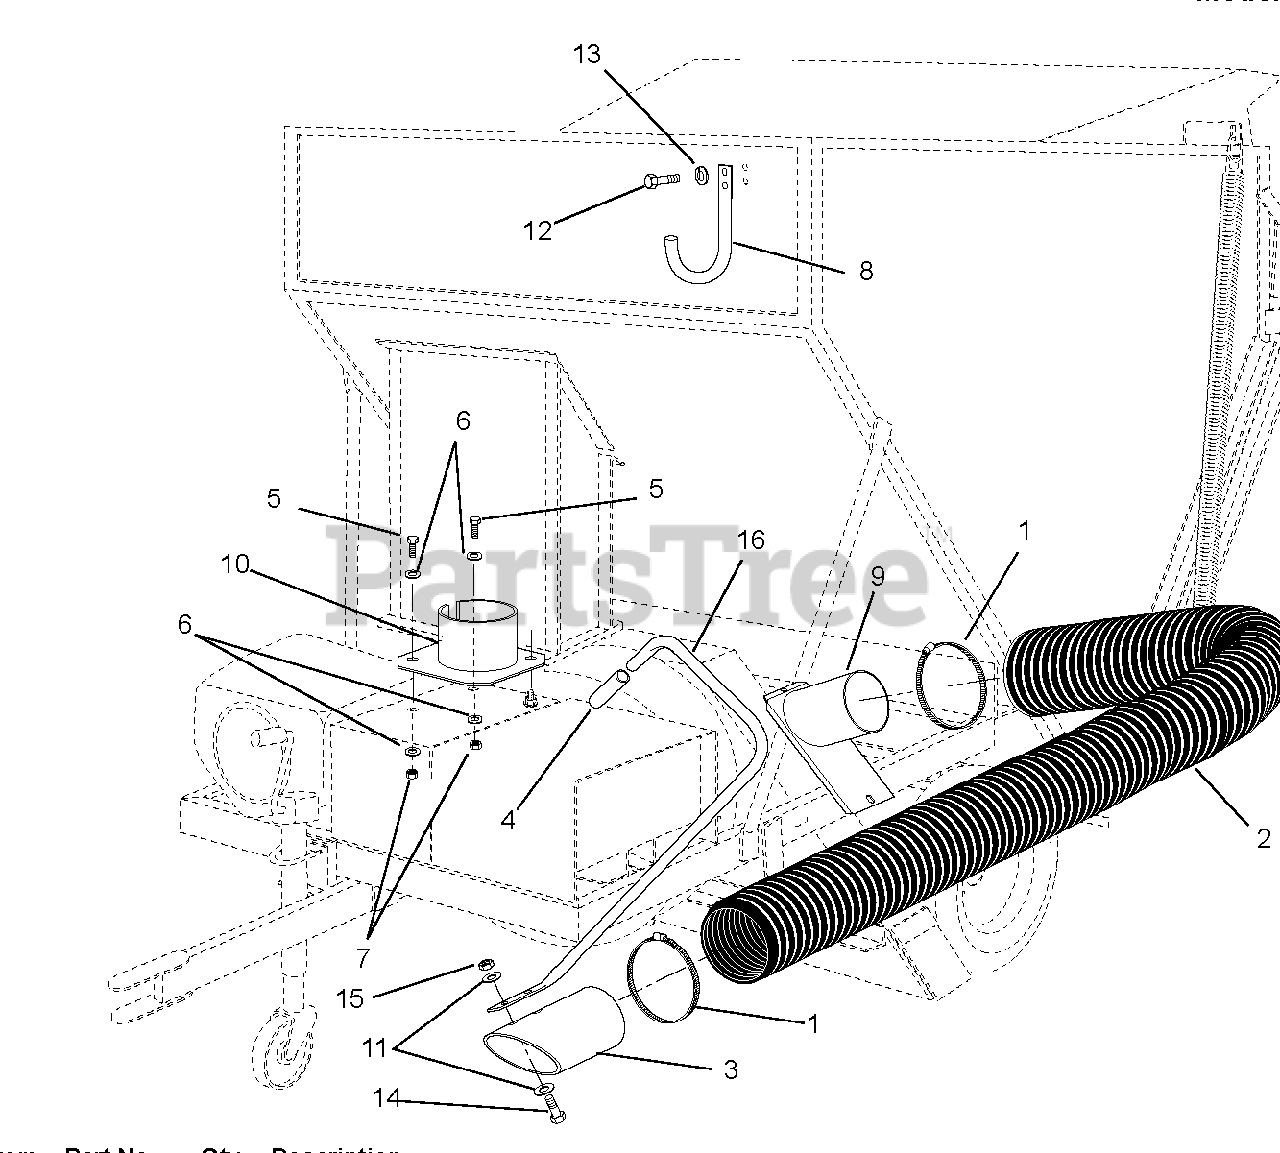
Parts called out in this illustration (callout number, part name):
1	Clamp, Hose
2	Hose, 6-In. x 10 ft.
3	Tube, Nozzle
4	Grip, Hand
5	Cap Screw, Hex Head .375-16 x 1
6	Washer, Flat .375
7	Nut, Nyloc Hex .375-16
8	Hanger, Flex Hose
9	Weldment, Adapter Tube
10	Holder, Nozzle
11	Washer, Flat .312
12	Cap Screw, Hex Head .375-16 x 2
13	Washer, Lock .375
14	Cap Screw, Hex Head .312-18 x 1
15	Nut, Hex Flange Lock .312-18
16	Handle, Nozzl
